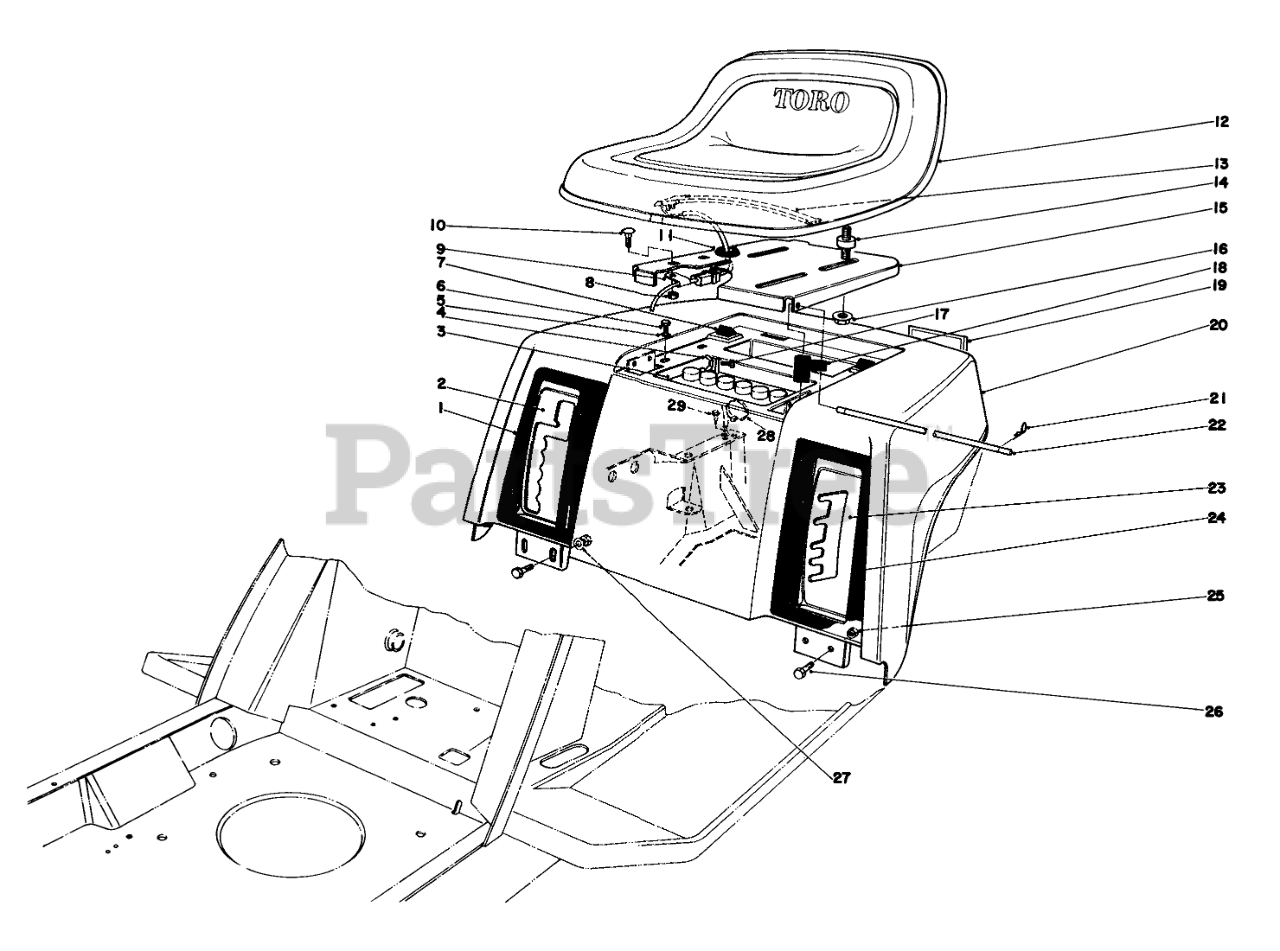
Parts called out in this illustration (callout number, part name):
1	Decal Transmission
2	DETENT PLATE B
3	Battery
4	NUT-WING
5	WASHER
6	SCREW-HWHTF
7	SEAT BUMPER
8	NUT-KEPS
9	CLAMP
10	SCREW-CARR
11	GROMMET
13	SWITCH-SEAT
14	ISOLATER-SEAT
15	SEAT SUPPORT R
16	NUT-HF
17	SCREW-HH
18	BOOT-TERMINAL
19	REFLECTOR
20	Rear Body Assembly (Incl. Ref. #1 & 24)
21	PIN-COTTER
22	PIVOT-SEAT
23	Quadrant Height of Cut
24	Decal Height of Cut
25	NUT-LOCK, NI
26	SCREW-HH
27	WASHER-PLAIN
28	TIE-CABLE
29	SCREW-HWHTF
